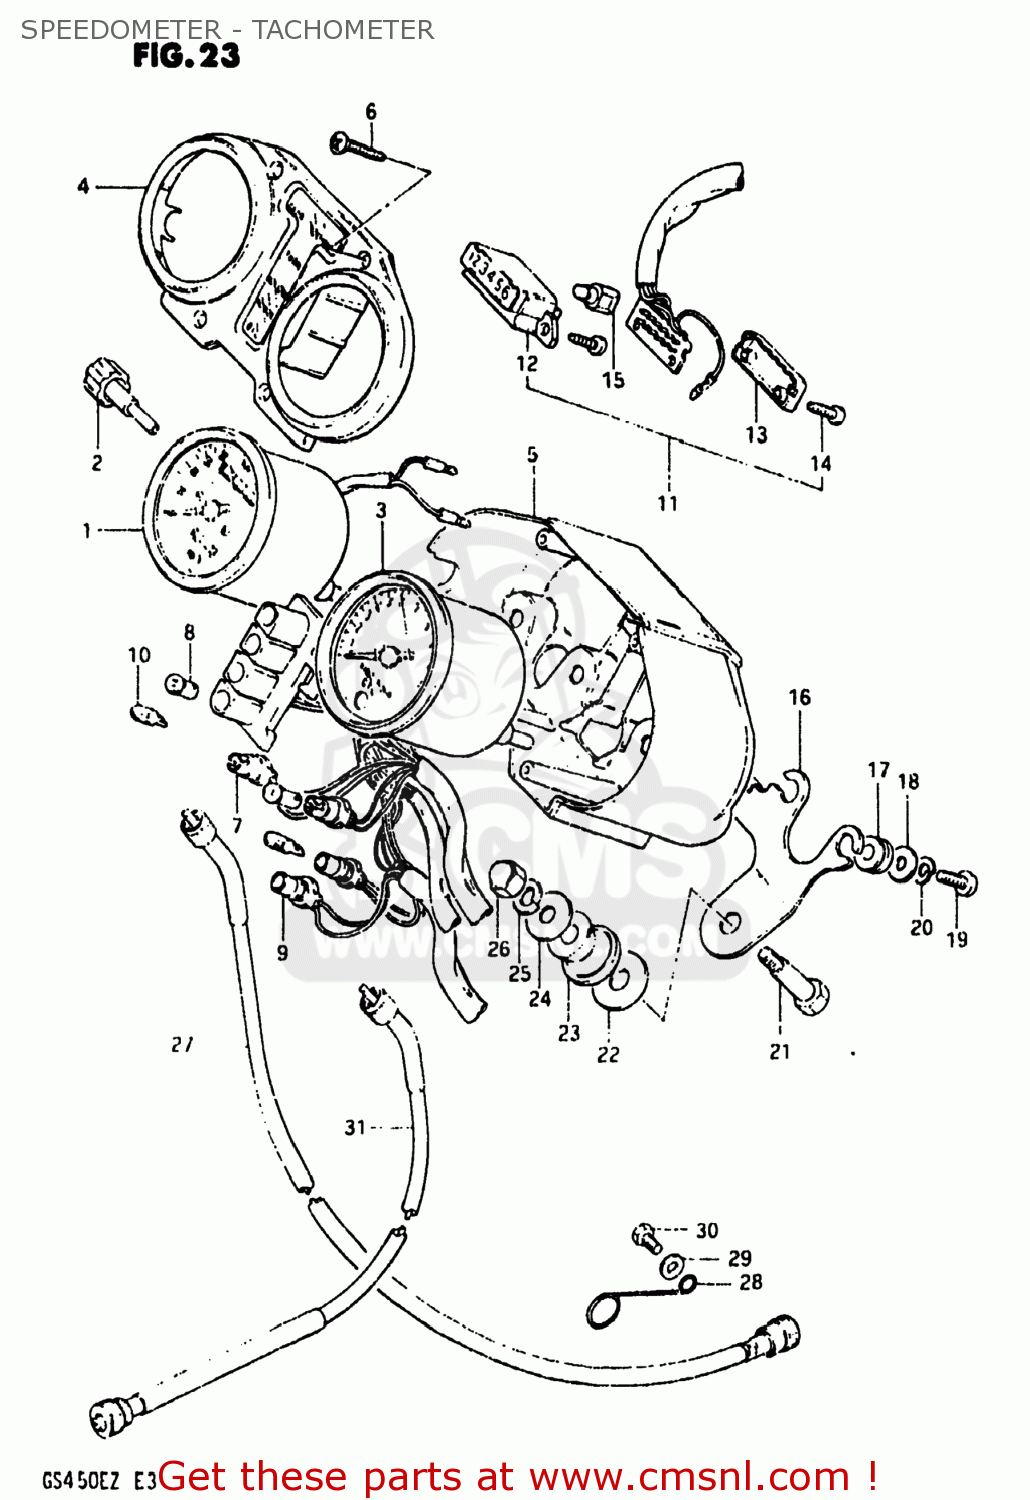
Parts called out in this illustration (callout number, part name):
1	SPEEDOMETER ASSEMBLY
2	KNOB,TRIP METER
3	TACHOMETER
4	CASE,METER,UPPER
5	VISOR,LWR
6	SCREW
7	SOCKET,SPEEDOMETER
8	BULB(12V3.4W,STANLEY,A72A)
9	SOCKET,SPEEDOMETER
10	BULB(12V3.4W,T10)
11	INDICATOR ASSEMBLY,GEAR POSITION
12	CASE,GEAR INDICATOR
13	COVER,LWR
14	SCREW,GEAR INDICATOR
15	BULB(14V1.12W)
16	BRACKET,METER
17	CUSHION
18	WASHER,METER
19	SCREW
20	LOCK WASHER
21	BOLT
22	WASHER
23	CUSHION,METER
24	WASHER(8.5X23X1.2)
25	LOCK WASHER
26	NUT
27	CABLE ASSEMBLY,SPEEDOMETER
28	CLAMP,SPEEDOMETER CABLE
29	WASHER
30	BOLT, UPPER
31	CABLE ASSEMBLY,TACHOMETER
